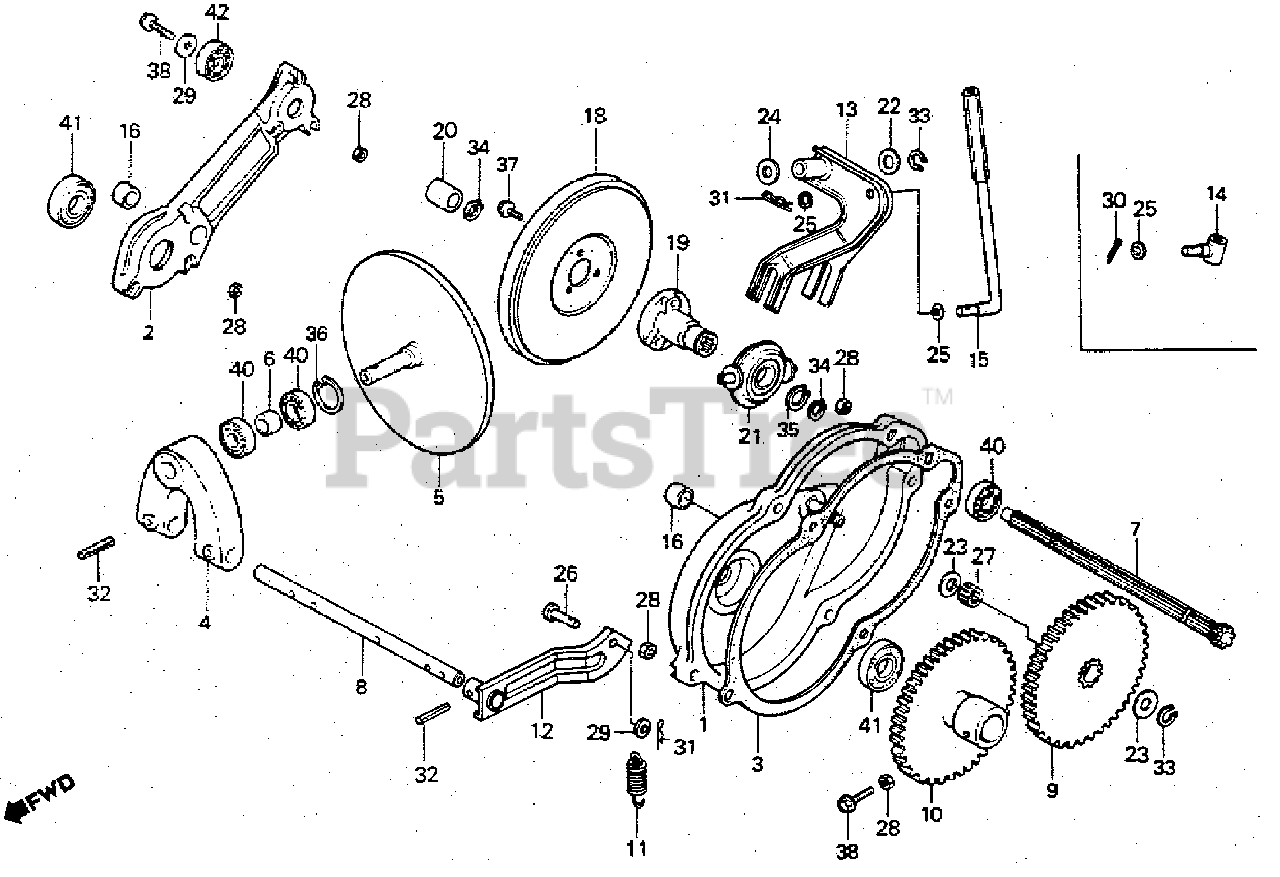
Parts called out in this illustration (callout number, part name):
1	CASE, L. TRANSMISSION (NOT AVAILABLE)
2	CASE, R. TRANSMISSION
3	GASKET, TRANSMISSION CASE
4	HOLDER, DRIVE DISK (NOT AVAILABLE)
5	DISK, DRIVE (NOT AVAILABLE)
6	COLLAR, DISK HOLDER (NOT AVAILABLE)
7	SHAFT, FRICTION DISK
8	SHAFT, DISK HOLDER (NOT AVAILABLE)
9	GEAR, COUNTER
10	GEAR, FINAL (NOT AVAILABLE)
11	SPRING, DRIVE DISK RETURN
12	ARM, CLUTCH
13	ARM, CHANGE
14	JOINT, CHANGE (NOT AVAILABLE)
15	JOINT, CHANGE (NOT AVAILABLE)
16	BUSH, DRIVE DISK SHAFT
18	DISK, FRICTION
19	BOSS, FRICTION DISK (NOT AVAILABLE)
20	COLLAR, FRICTION
21	ROLLER (NOT AVAILABLE)
22	WASHER, THRUST (12MM)
23	WASHER C, THRUST (12MM) (0.7)
24	WASHER, THRUST (12MM)
25	WASHER, PLAIN (7MM) (NOT AVAILABLE)
25	COLLAR, CHANGE JOINT
26	PIN, CLUTCH ARM
27	BEARING, NEEDLE (12MM)
28	NUT, HEX. (6MM)
29	WASHER, PLAIN (6MM)
30	PIN, COTTER (3.0X18)
31	PIN, LOCK (6MM)
32	PIN, SPRING (6X25)
33	CIRCLIP (OUTER) (12MM)
34	CIRCLIP (OUTER) (15MM)
35	CIRCLIP (OUTER) (22MM)
36	CIRCLIP (INNER) (32MM)
37	BOLT, FLANGE (6X12)
38	BOLT, FLANGE (6X16)
40	BEARING, RADIAL BALL
41	BEARING, RADIAL BALL (6004UU)
42	BEARING, RADIAL BALL (6201UU)
